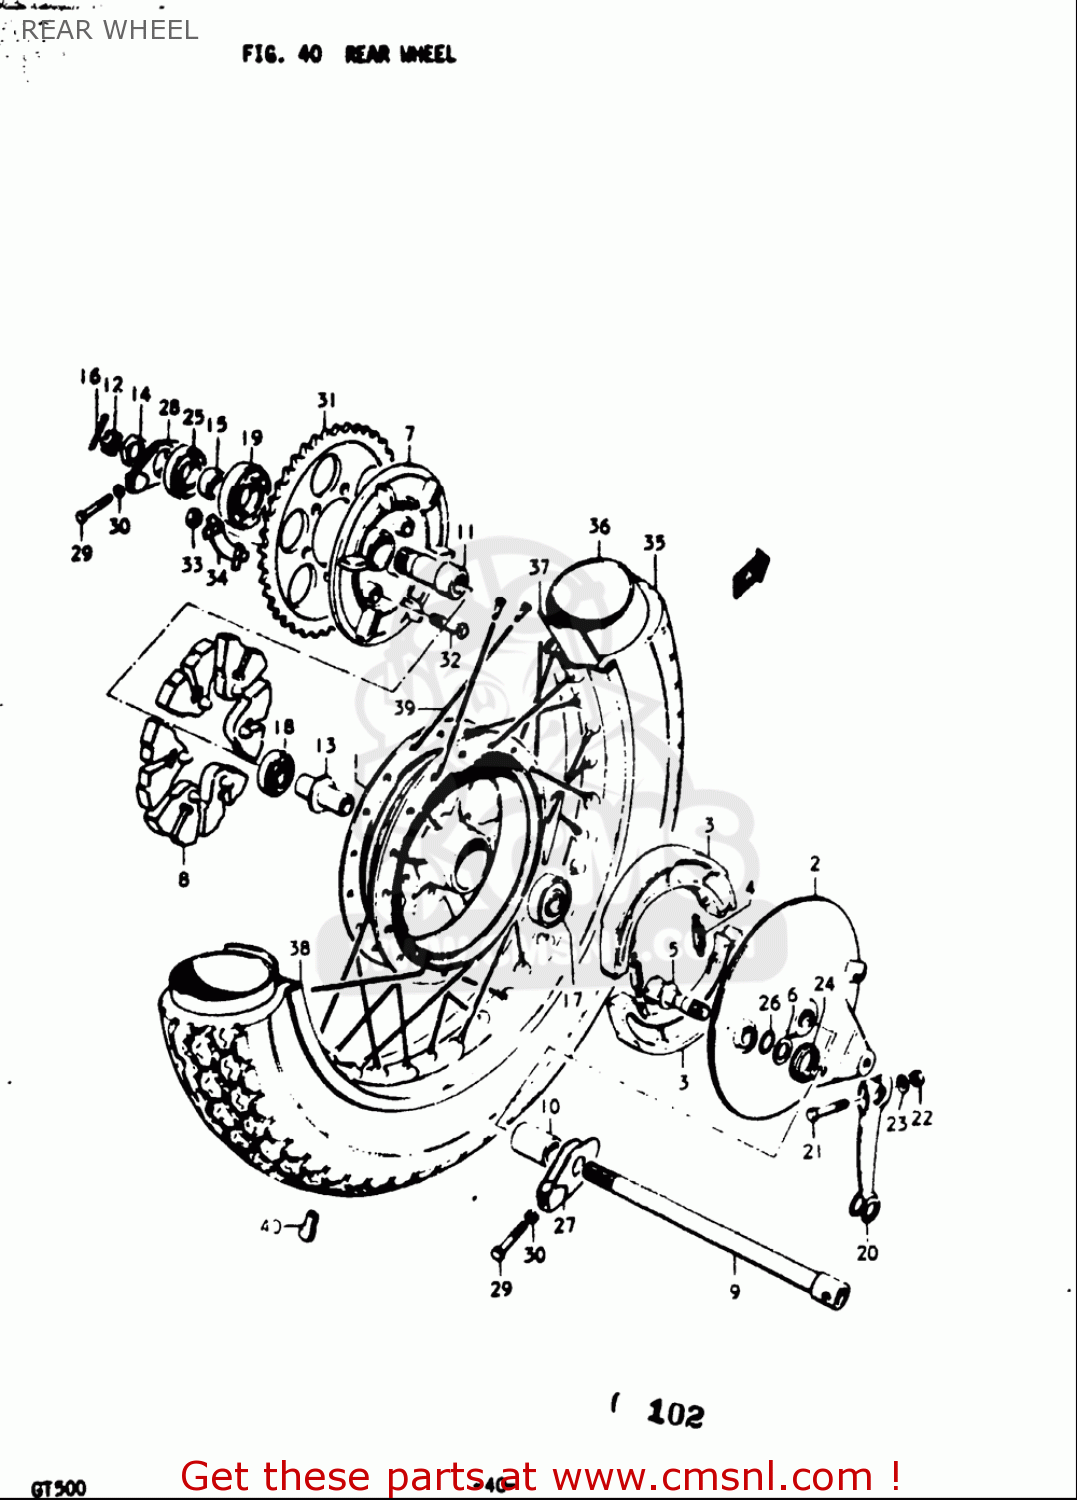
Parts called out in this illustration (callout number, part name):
3	SHOE SET,BRAKE (NAS)
4	SPRING,BRAKE SHOE
6	WASHER(15.5X24X1.6)
8	ABSORBER,RR HUB SHOCK
9	AXLE,REAR
12	NUT 16MM
13	SPACER
14	NUT
15	SPACER (25X30.5X11.3)
16	PIN, COTTER
17	BEARING
18	BEARING
19	BEARING(25X52X15)
21	BOLT
22	NUT
23	WASHER
24	SPRING
25	SEAL,OIL(30.5X52X8)
26	O RING(D:2.4,ID:14.8)
